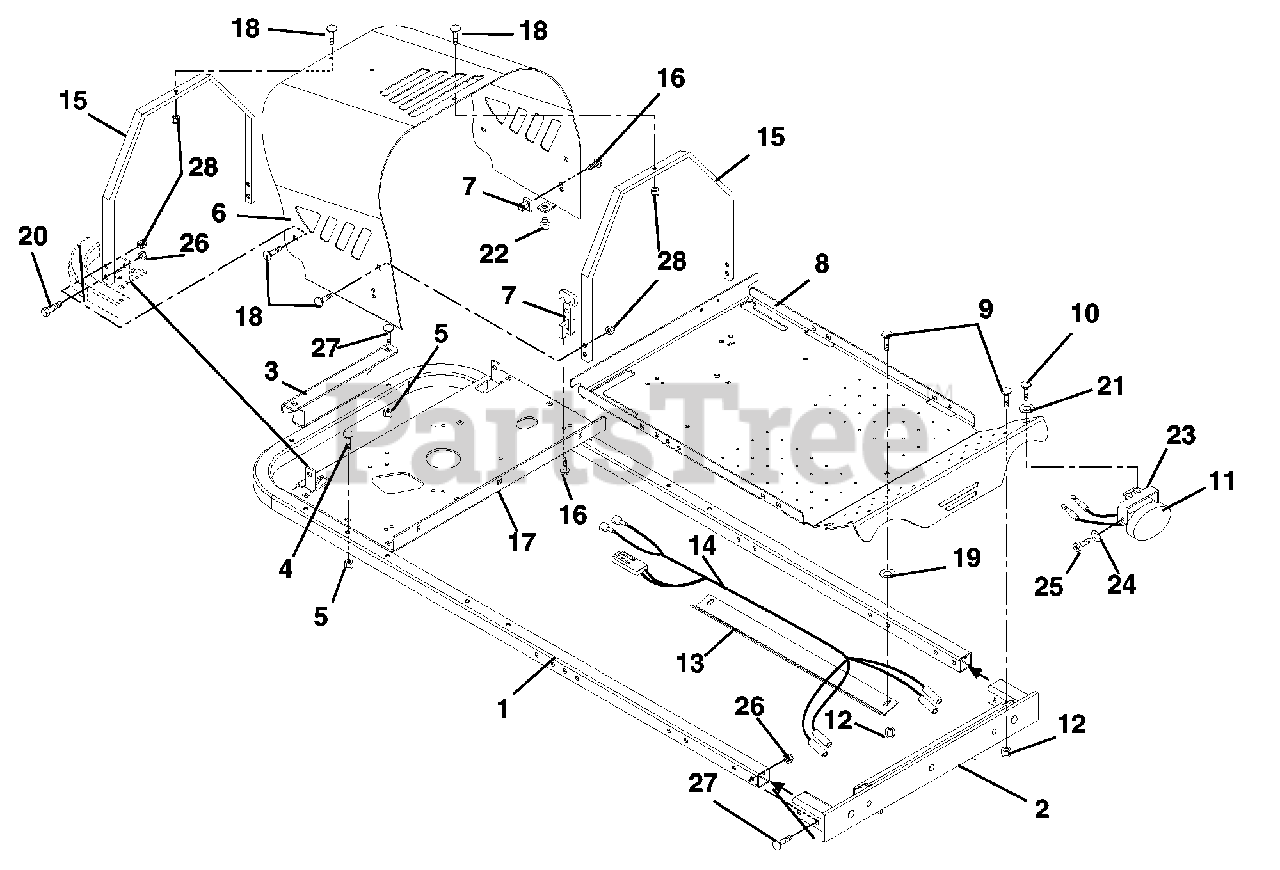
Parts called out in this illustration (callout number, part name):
1	Tube, Frame
2	Weldment, Axle Mount
3	Trailer Hitch with Decal
4	Bolt, Round Head Square Neck .38-16 x 2.5 Grade 5
5	Nut.38-16 Flange Nyloc
6	Hood, Zoom
7	Latch, Rubber
8	Footrest
9	Bolt, Round Head Square Neck .31-18 x 1.00 Grade 5
10	Screw-Cap Button Head .31-18 x .50 Grade 5
11	Assembly, Light
12	Nut 5/16-18 Flange Nyloc
13	Bracket, Harness
14	Harness, Light
15	Brace, Hood
16	Screw-Machine 10-24 x .50 Hex Washer Head
17	Plate, Engine
18	Bolt, Round Head Square Neck .31-18 x .62
19	Washer, Flat Steel .38 x .87 x .179
20	Bolt, Shoulder .375-16 x .135
21	Washer, Locking .31 x .078 Regular
22	Button Bumper
23	Bracket, Light
24	Washer, Locking 4MM x 1MM Regular Cone Lock
25	Screw, Socket Head Cap M4 x .07 x 8
26	Nut-Locking-Top-Flange .38-16
27	Bolt-Round Head Square Neck .38-16 x 2.25 Grade 5
28	Nut-Locking-Top-Flange .31-18
